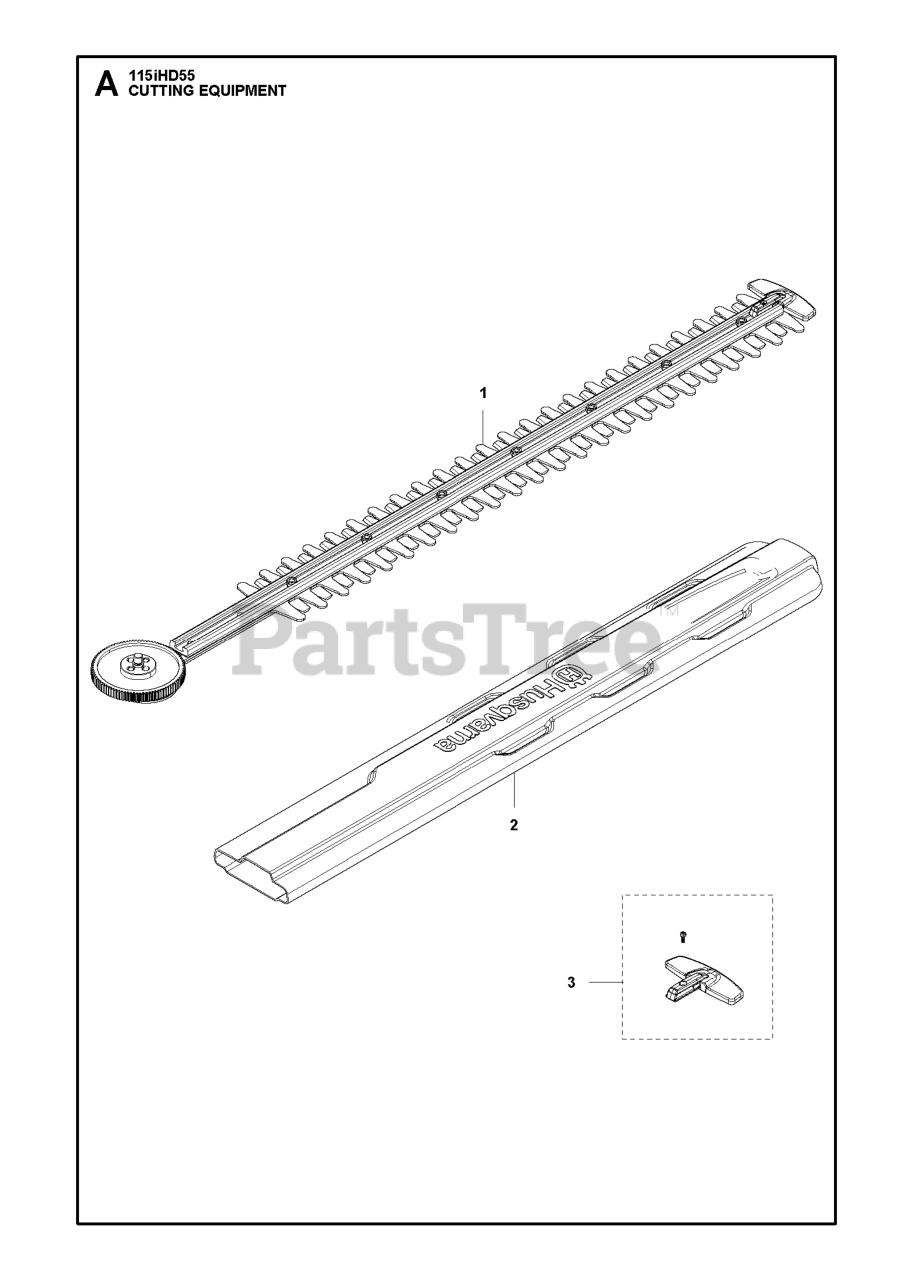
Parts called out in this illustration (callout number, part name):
1	DRIVER ASSY US VERSION
2	BLADE SLEEVE FOR US MARKET
3	TIP PROTECTION KOMPL
